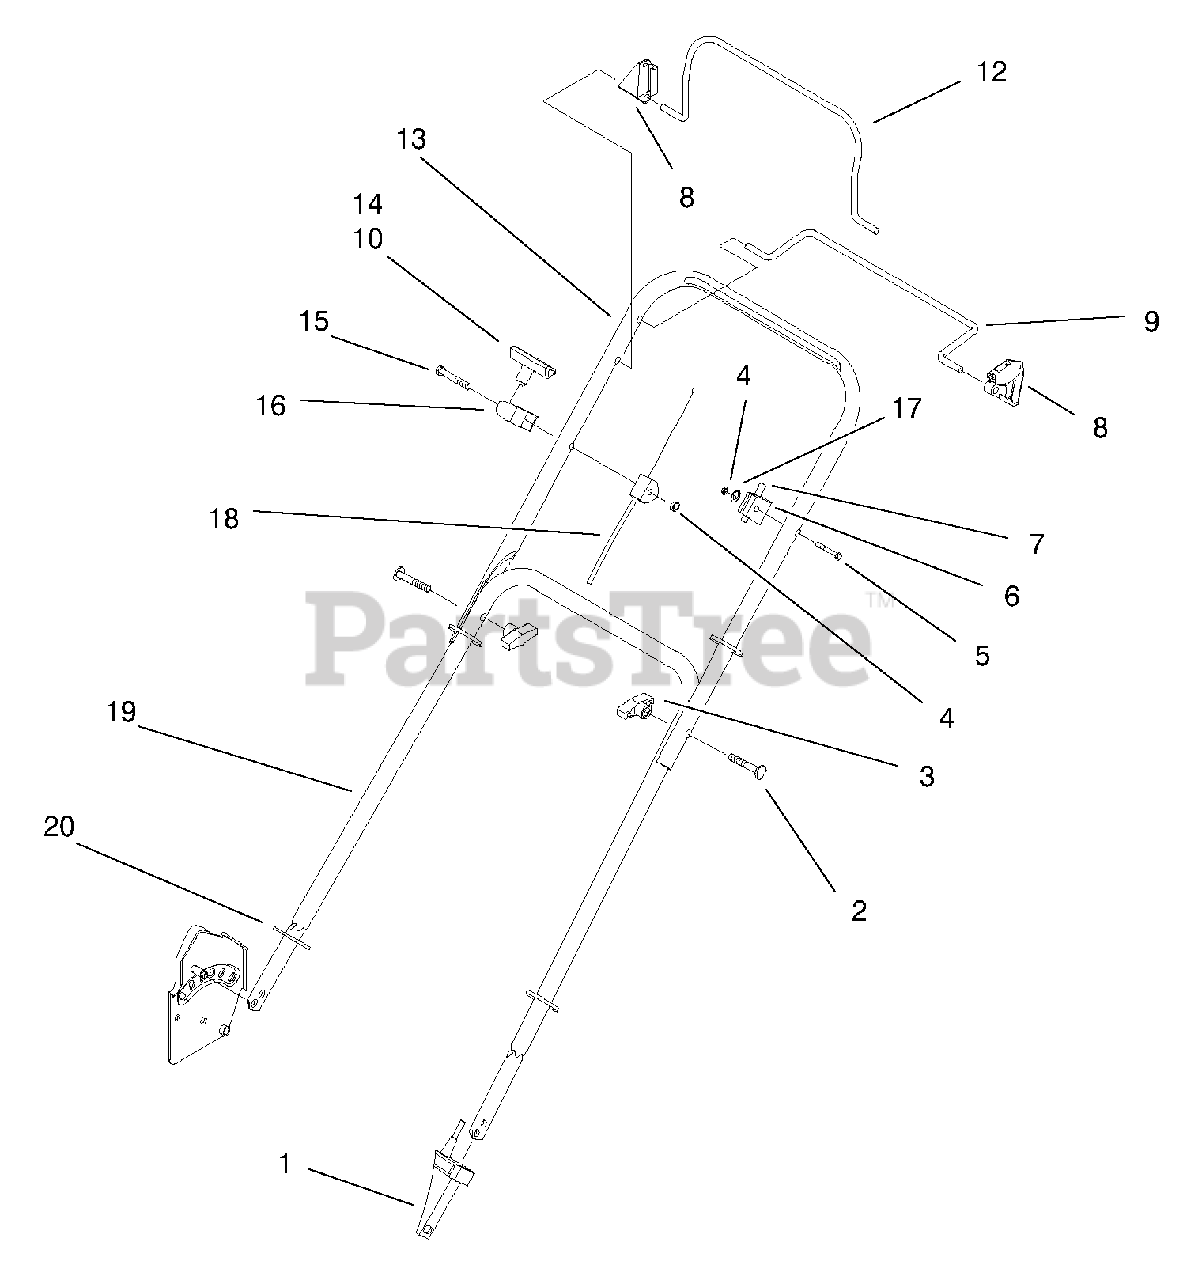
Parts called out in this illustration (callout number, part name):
1	Anchor-Cable
3	Knob-Handle
4	Nut-Lock, NI
5	Screw-Handle
6	Anchor-Upper Sp Cable
7	Cable-Ground Speed
8	Stop-Pivot
9	Bail-Control
10	Staple-Handle
12	Bail-Brake
13	Handle-Upper
14	Handle-Starter
15	Screw-HH
16	Rope-Guide
17	Washer-Flat
18	Brake Cable ASM.
19	Section-Lower Handle
20	Guard-Handle
